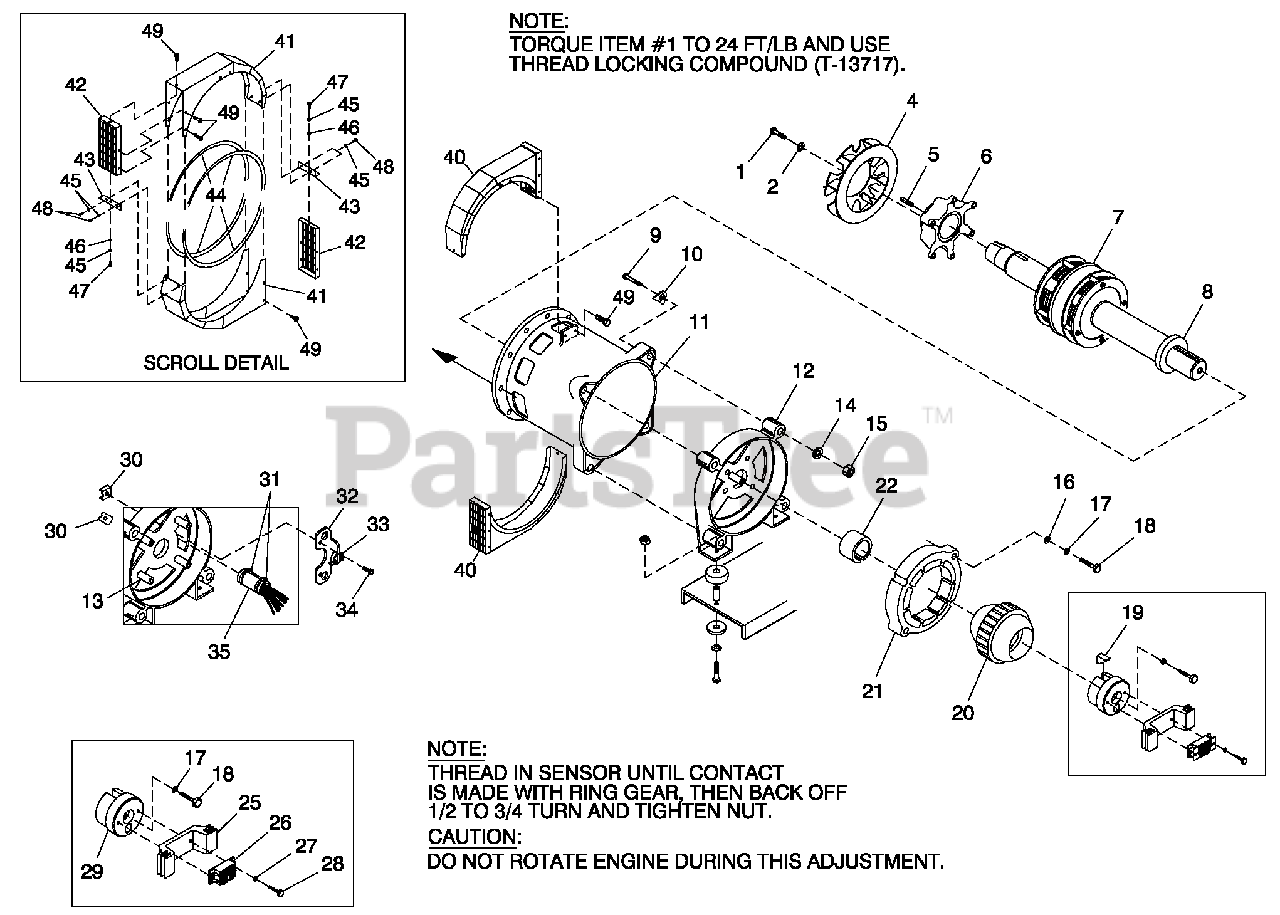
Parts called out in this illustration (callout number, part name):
1	SCREW HHC M8-1.25 X 20 G10.9
2	WASHER LOCK M8-5/16
4	FAN SAE ALTERNATOR (G/B)
5	KEY SQ 3/8X1-9/16 STEEL
6	HUB DRIVE 390 SAE GB
7	RTR 390 100KB3 GB SAE TECHUM
8	BEARING BALL 6212 SEALED
9	SCREW HHC M14-2.0 X 140 G8.8
10	WASHER 390 SAE ALT.
11	STR-390-80LB3 SAE
12	CARRIER REAR BRG 15"
13	PIN DOWEL 1/2 X 1-1/4
14	WASHER LOCK M14
15	NUT HEX M14-2.0 G8 YEL CHR
16	WASHER FLAT M12
17	WASHER LOCK M12
18	SCREW HHC M12-1.75 X 60 G10.9
19	KEY SQ 3/8 X 3-1/4 STEEL
20	ASSY EXCITER 2.00" STK
21	EXITER FIELD 2" LG SPD CONN
22	COLLAR SLIP FIT 390 MM
25	BRIDGE SUPPORT DIODE 15"
26	ASSY BRIDGE RECTIFIER
27	WASHER SHAKEPROOF INT #8
28	SCREW HHM #8-32 X 7/8
29	CAP END ROTOR 390MM
30	PLATE NUT
31	TIE WRAP UL 14.6 X .14 NATL
32	BRACKET-STATOR WIRE
33	CLAMP HOSE #36 1.88-2.7
34	SCREW HHC 5/16-18 X 1-1/4 G5
35	SLEEVE RUBBER
40	ASSY SCROLL 390 SAE
41	SHROUD ALT SHEET METAL
42	SCREEN SHROUD SAE
43	BRKT TENSIONER SAE SCROLL
44	TRIM VINYL BLACK 1/8 GP
45	WASHER LOCK M6-1/4
46	WASHER FLAT 1/4-M6 ZINC
47	SCREW HHC M6-1.0 X 25 G8.8
48	SCREW HHC M6-1.0 X 16 G8.8
49	SCREW SWAGE 1/4-20 X 1/2 ZYC
